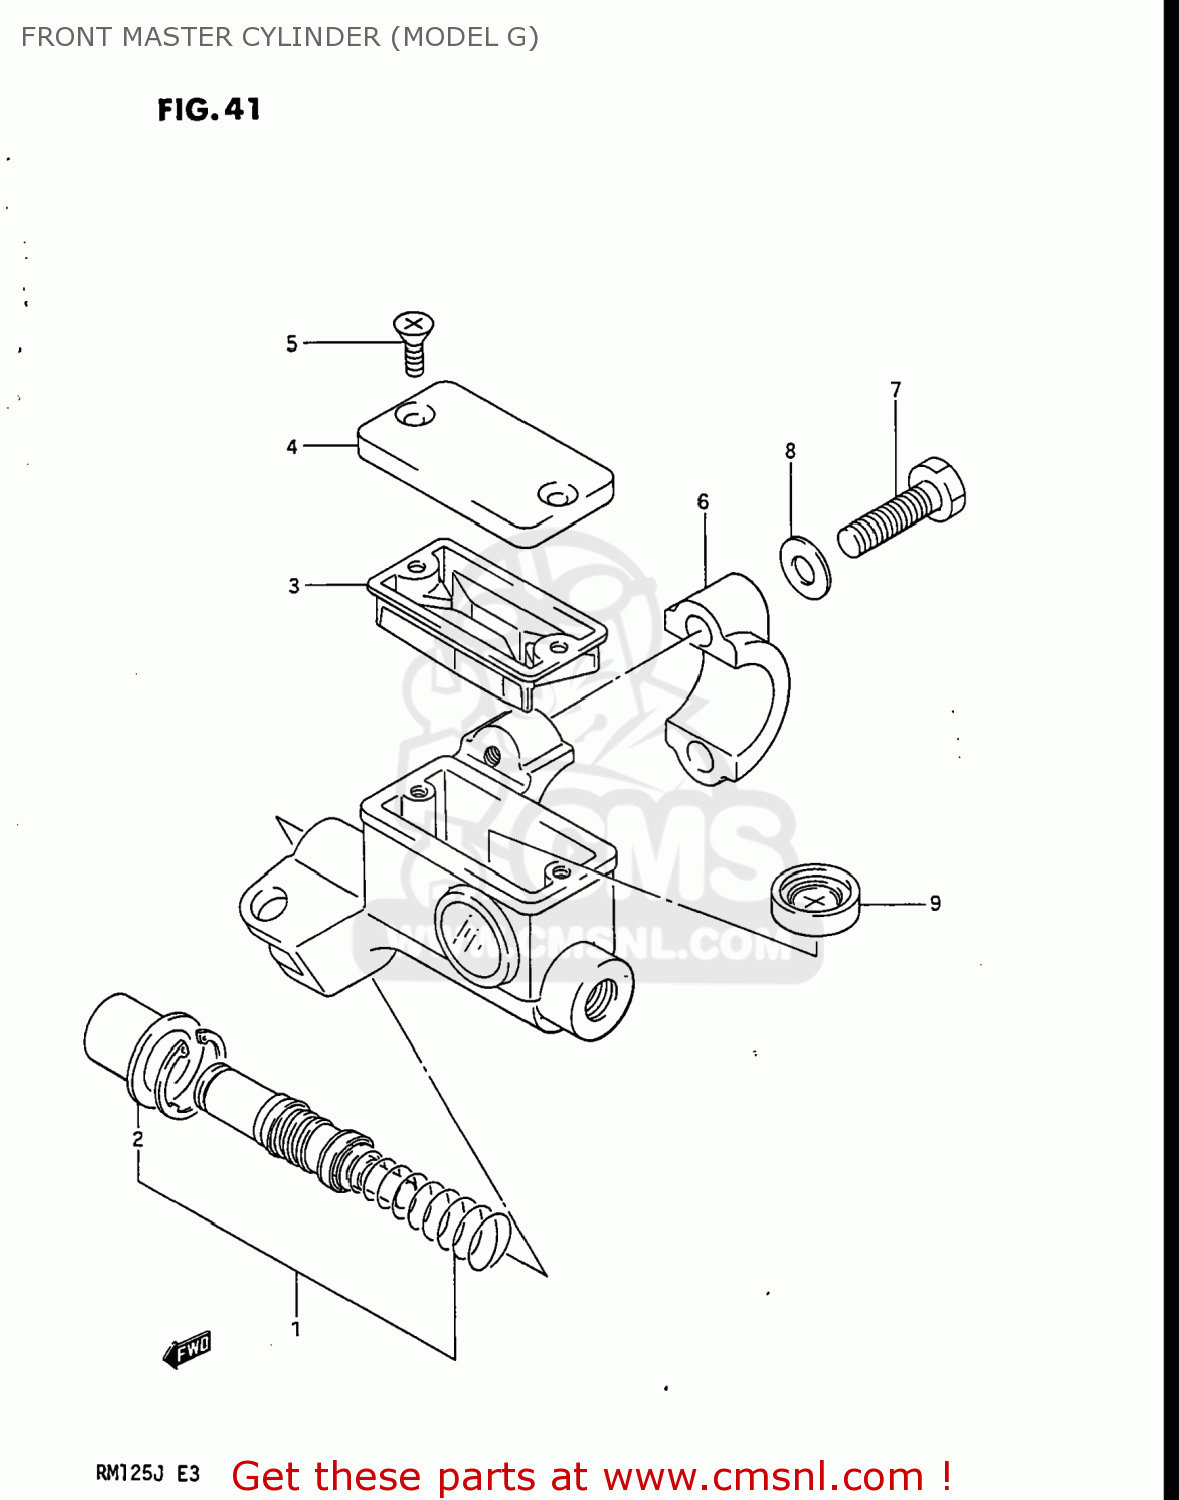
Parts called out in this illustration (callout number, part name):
1	PISTON/CUP SET,FR MASTER
2	BOOT
3	DIAPHRAGM
4	CAP
5	SCREW
6	HOLDER,MASTER CYLINDER
7	BOLT
8	WASHER
9	SEPARATOR
